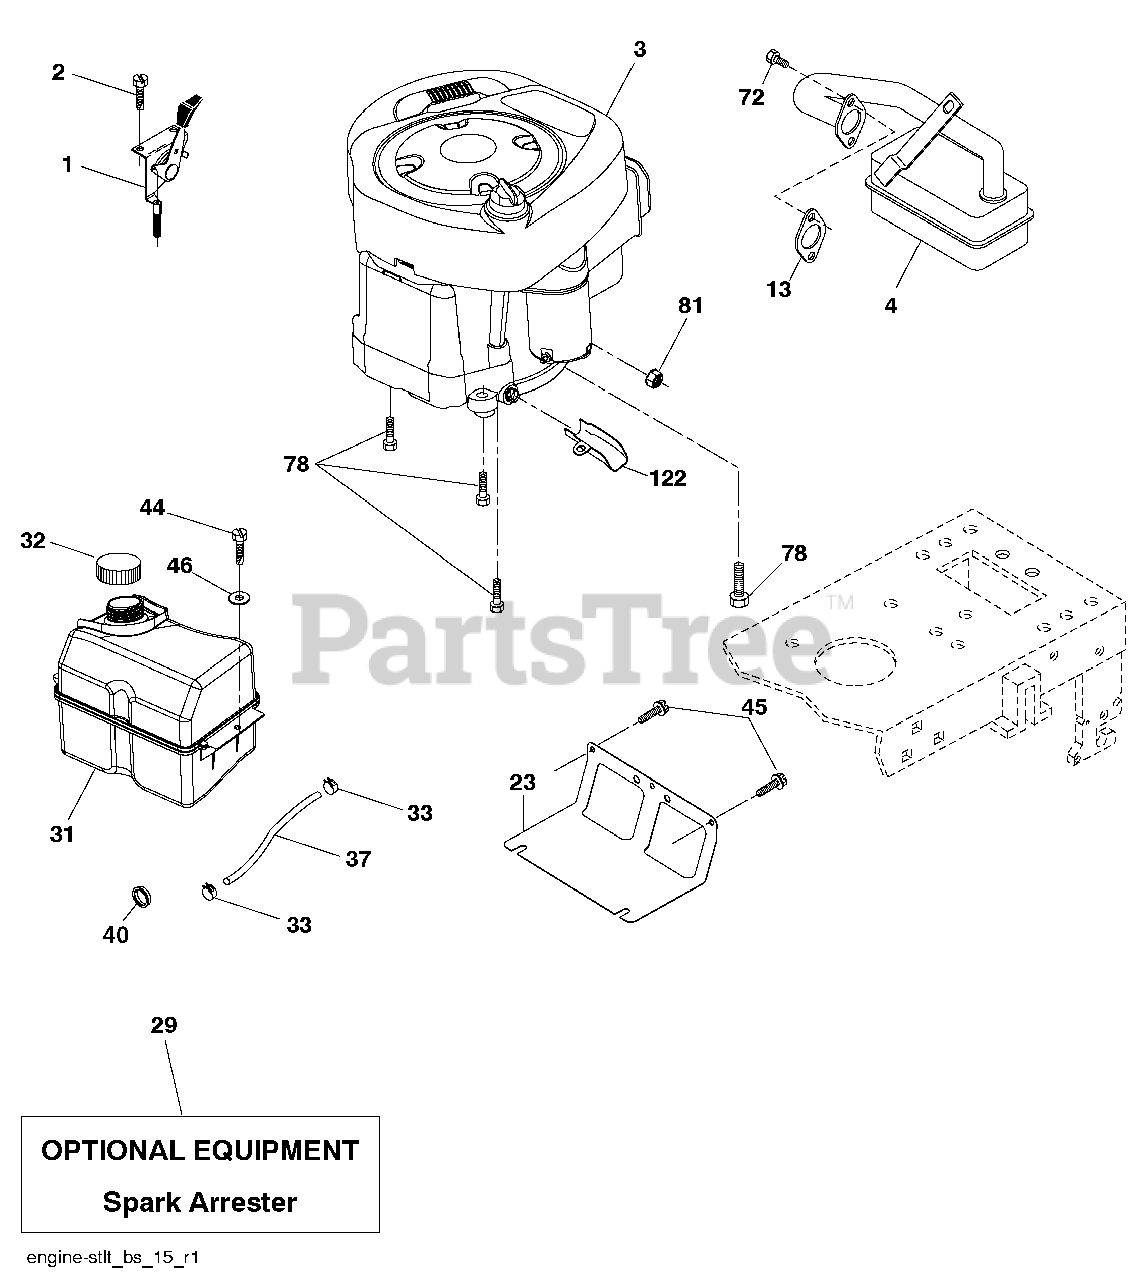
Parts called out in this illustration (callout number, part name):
1	Control Th/ch Flag
2	Screw Hex Thd Cut 1/4-20 x 1/2
4	Muffler Exhaust B&S
13	Gasket Eng 1 313 Id Tin Plated
23	Shield BRN/DBR Guard
29	Kit Spark Arrestor (Flat Scrn)
31	Tank Fuel Front
32	Cap Asm Fuel
33	Clamp Hose
37	Line Fuel 20"
40	Bushing Snap
44	Screw Thdrol 1/4-20 x 3/4
45	Screw Hex Wsh Thdrol 3/8-16
46	Washer 9/32 x 7/8 x 16 Ga.
72	Screw Socket Hd 5/16-18 x .75
78	Screw 3/8-16 x 1-1/4
81	Nut Keps Hex 1/4-20 unc
122	Extension Drain Oil
